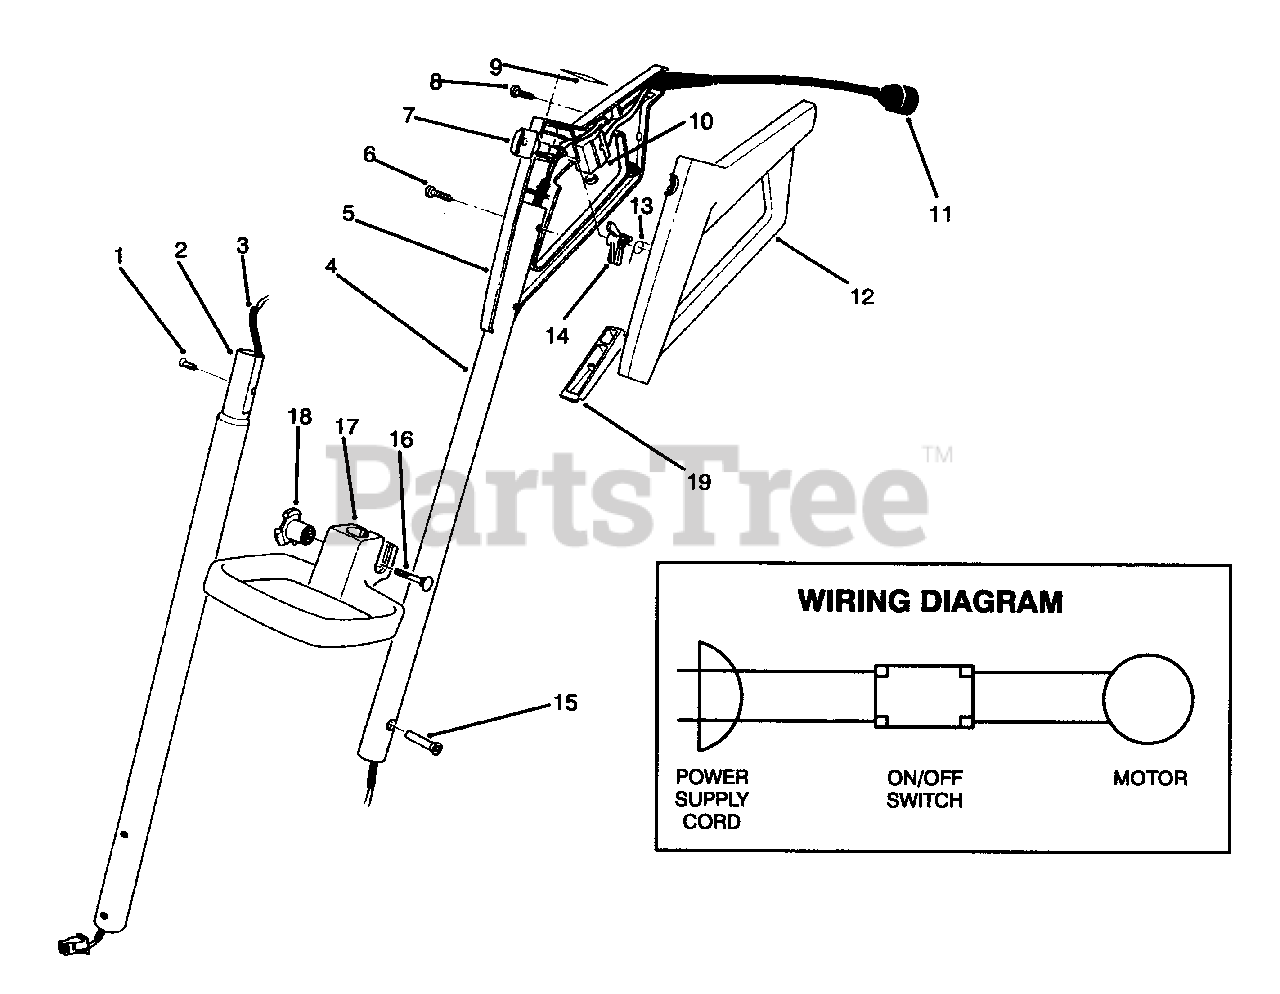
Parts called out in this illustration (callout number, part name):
1	Screw-Shoulder
2	Tube-Lower Handle
3	Wire Harness
4	Tube-Upper Handle
5	Grip-Control R.H.
6	Screw-Pan Head
8	Screw-Pan Head
9	Decal-Control Grip
11	Cord-Supply
12	Grip-Control L.H.
15	Nut-Countersunk
16	Bolt-Carriage
17	Handle-Adjustable
19	Switch Bar
